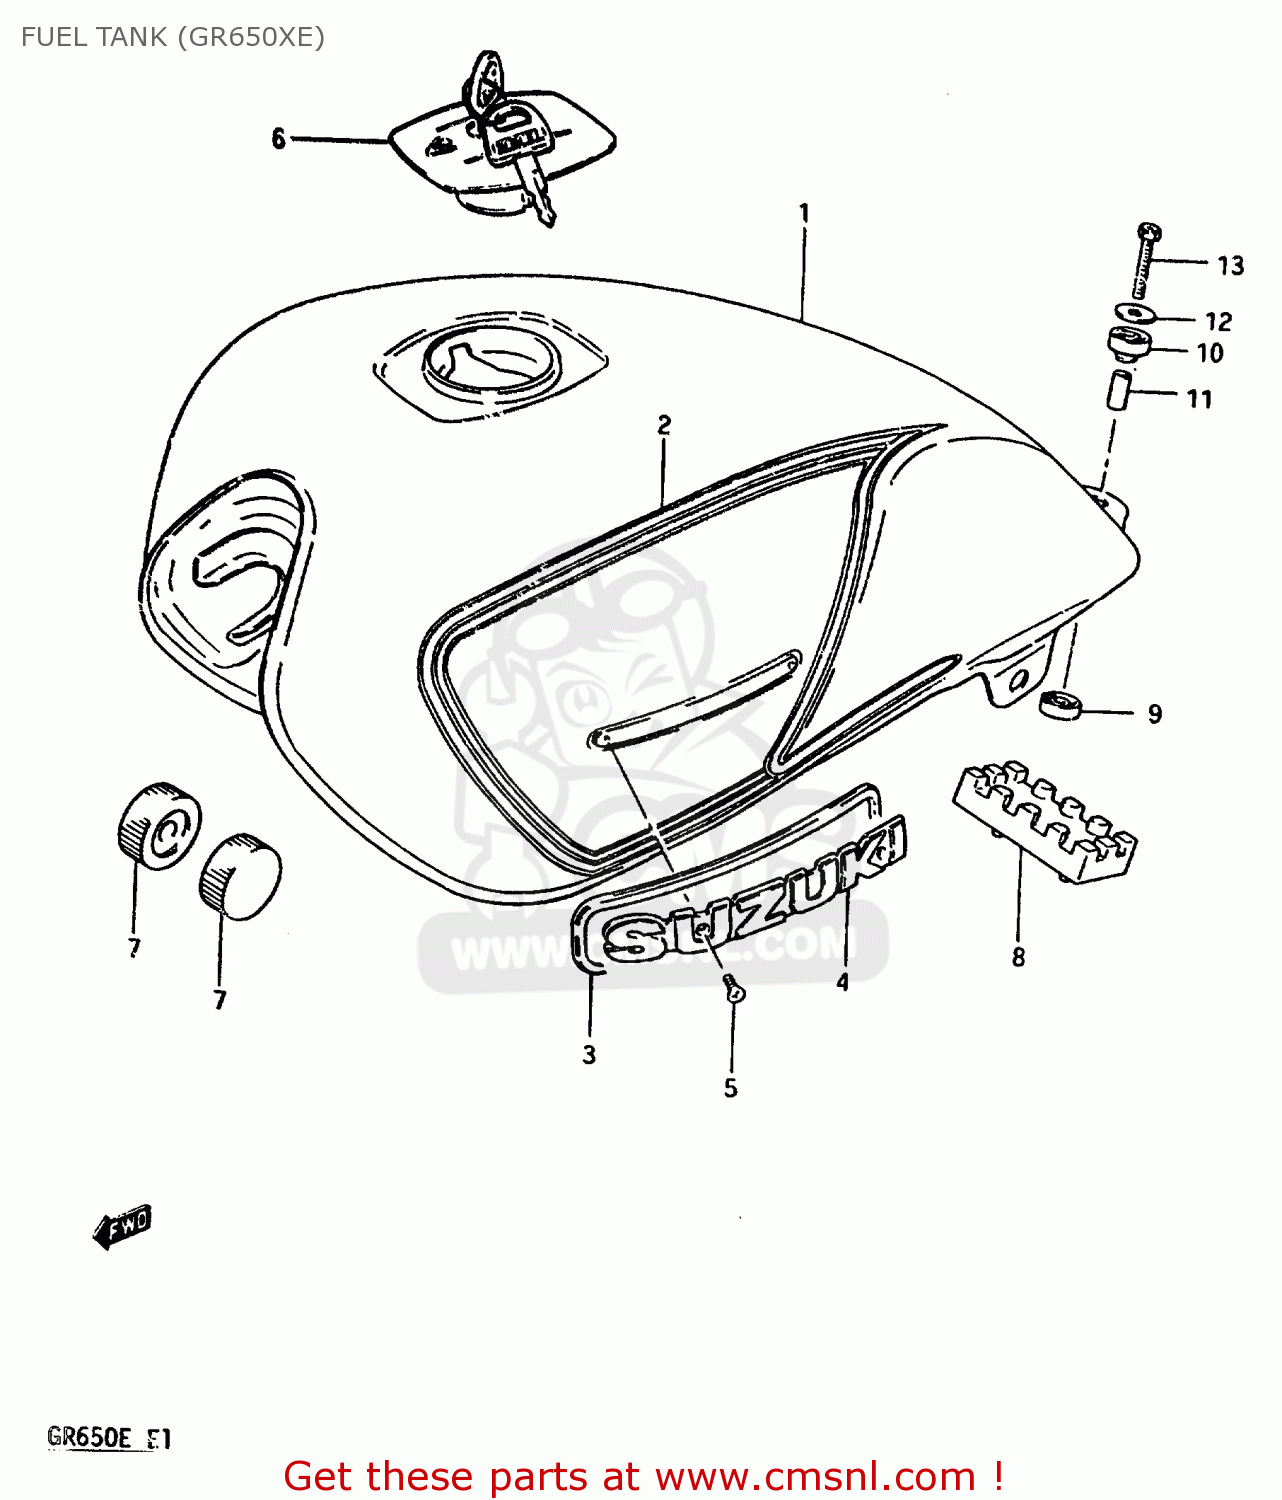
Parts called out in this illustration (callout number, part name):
1	TANK, FUEL (RED)
2	TAPE SET
3	CUSHION
4	EMBLEM,FUEL TANK
5	SCREW 3X6
6	CAP SET,FUEL TANK
7	CUSHION
8	CUSHION,FUEL TANK CTR
9	CUSHION
10	CUSHION
11	SPACER (6.4X9X20)
12	WASHER (6.5X24X1.6)
13	BOLT
